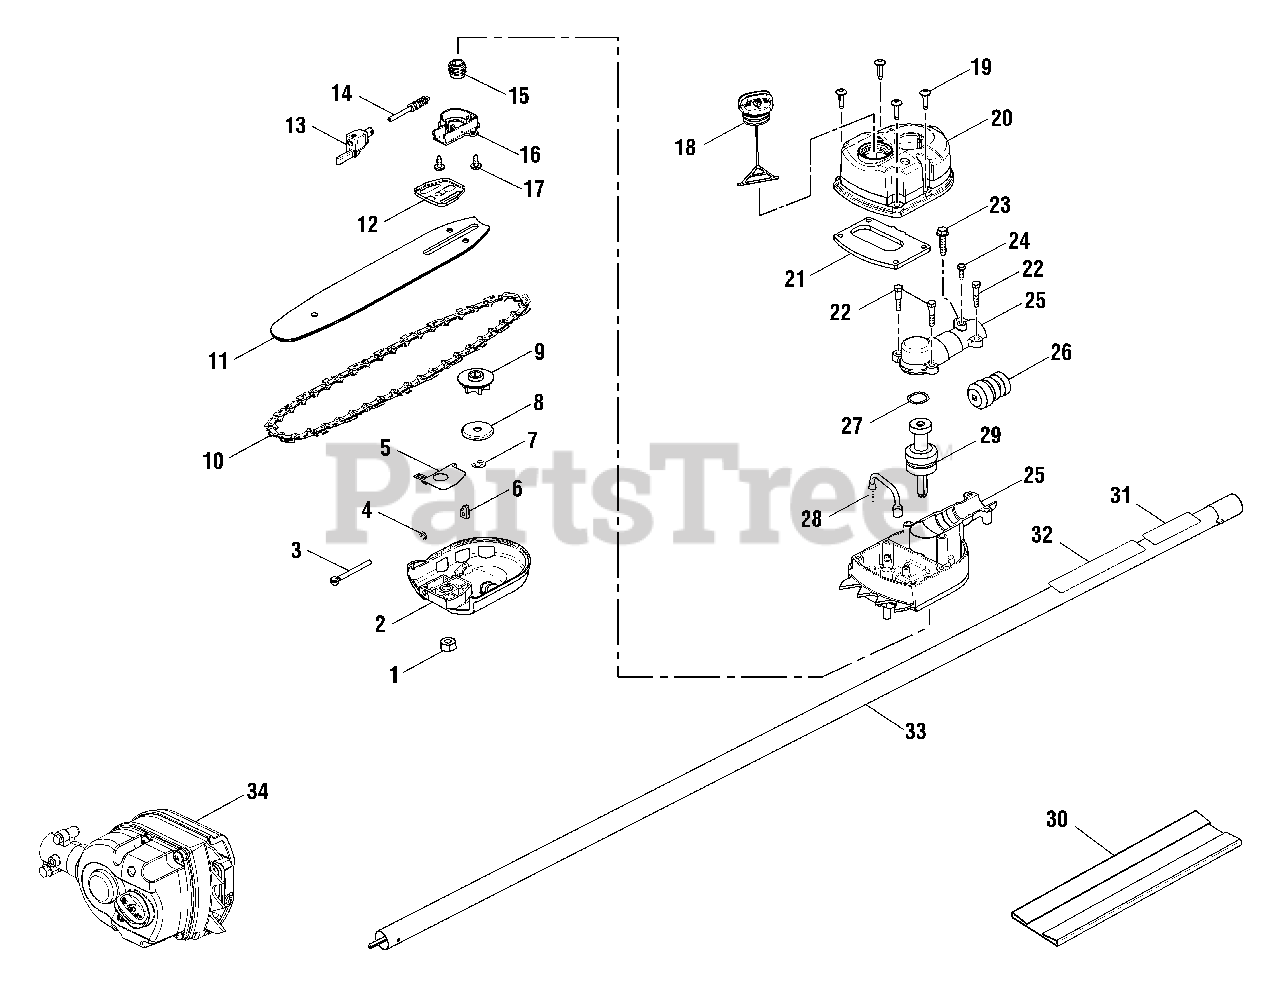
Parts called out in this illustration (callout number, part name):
1	HEX NUT (M8)
2	BAR CLAMP ASSEMBLY
3	GUIDE BAR ADJUSTMENT SCREW (M5 X 50 mm)
4	RETAINING RING (4 mm)
5	GUIDE BAR PLATE
6	GUIDE BAR ADJUSTING PIN
7	E-RING (6 mm)
8	CUPPED WASHER
9	SPROCKET
10	CHAIN (3/8, .043, 10)
11	GUIDE BAR
12	BAR PAD PLATE
13	OIL PUMP SEAL ASSEMBLY
14	OIL PINION GEAR & PLUNGER
15	WORM GEAR
16	OIL PUMP HOUSING W/CAM PIN ASSEMBLY
17	SCREW (M5 X 3 mm)
18	OIL CAP WITH RETAINER (PKG.)
19	SCREW (M5 X 18 mm)
20	OIL TANK COVER ASSEMBLY
21	OIL COVER GASKET
22	SCREW (M5 X 25 mm, SHOULDER SCREW)
23	SCREW (M5 X 25 mm)
24	SCREW (10-24 X 1/2 in. HEX WASHER HD. TRI-LOBULAR)
25	GEAR CASE & COVER ASSEMBLY
26	PINION GEAR ASSEMBLY
27	WAVY WASHER
28	PICK-UP TUBE ASSEMBLY
29	OUTPUT SHAFT ASSEMBLY
30	BLADE COVER
31	EXPAND-IT LABEL
32	WARNING LABEL
33	PRUNER BOOM ASSEMBLY (55 in.)
34	PRUNER GEAR HEAD
